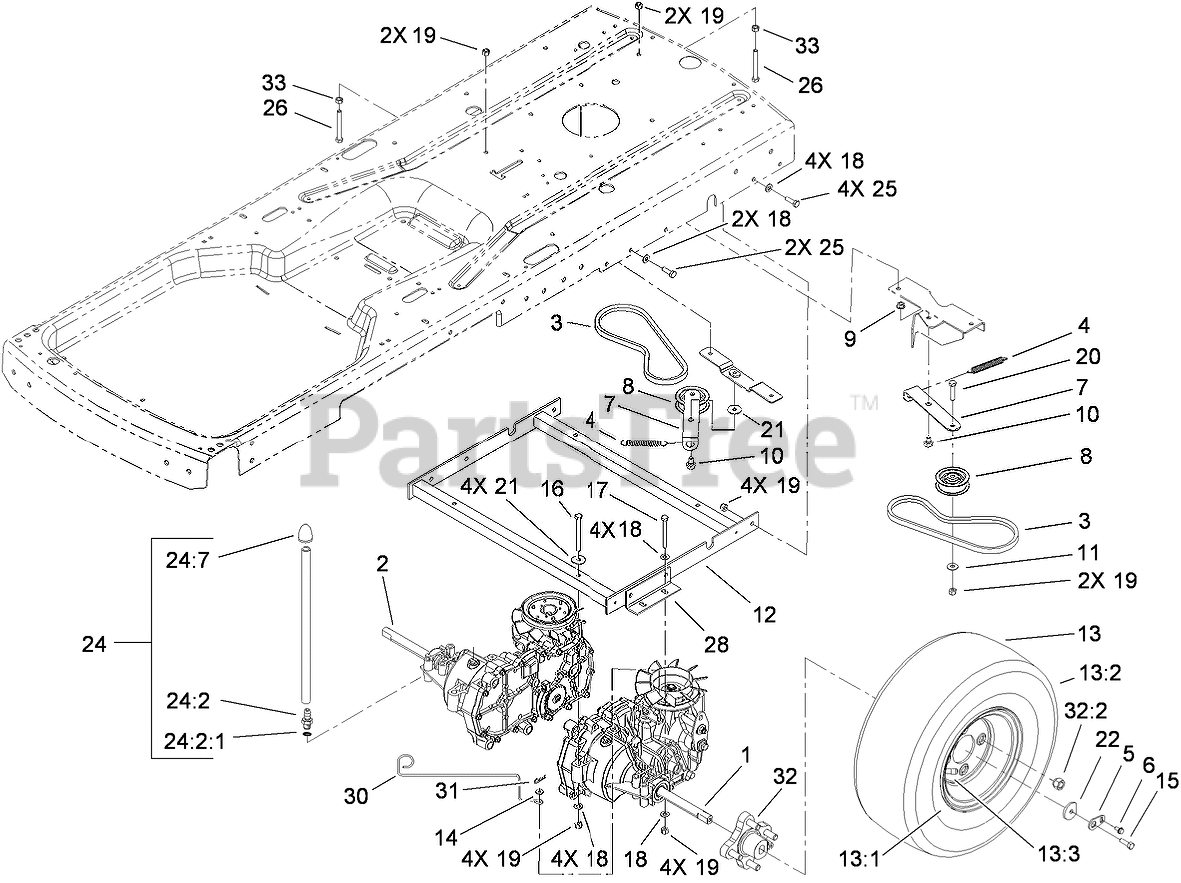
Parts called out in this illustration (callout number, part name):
1	TRANSAXLE-HYDRO, LH
2	TRANSAXLE-HYDRO, RH
3	V-BELT
4	SPRING
5	TAB-LOCKING
6	SCREW-HHF
7	ARM-IDLER
8	PULLEY-IDLER
9	NUT-HF
10	BOLT-SHOULDER
11	WASHER-FLAT
12	HYDRO MOUNT ASM
13	WHEEL AND TIRE ASM
13:3	STEM-VALVE
13:99	TUBE-TIRE
14	WASHER-FLAT
15	SCREW-HH
16	SCREW-HH
17	SCREW-HH
18	WASHER-PLAIN
19	NUT-LOCK, NI
20	SCREW-HH
21	WASHER-PIVOT
22	WASHER-WHEEL
24	VENT HOSE ASM
24:2	FITTING ASM
24:2:1	O-RING
24:7	CAP VENT ASM
25	SCREW-HH
26	SCREW-HH
28	SUPPORT-HYDRO
30	ROD-BYPASS
31	PIN-COTTER
32	HUB ASM
32:2	NUT-LUG
33	NUT-HEX
